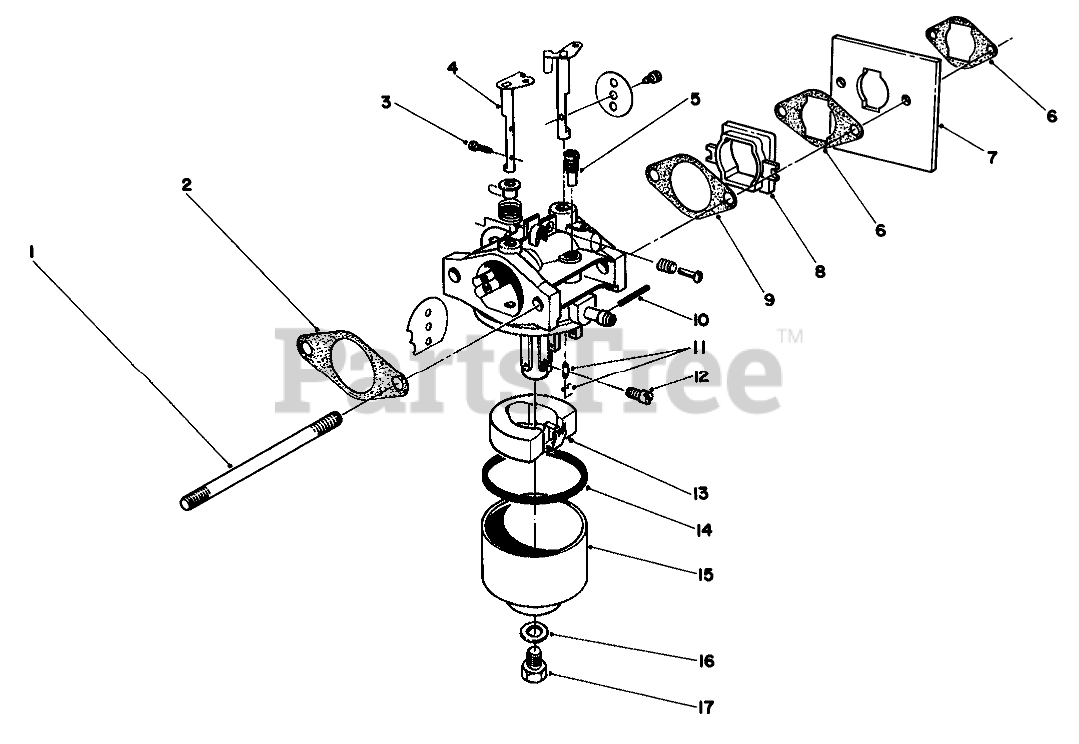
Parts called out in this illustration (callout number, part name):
1	CARB STUD BOLT
2	GASKET-AIR CLEANER
3	SCREW
4	SHAFT-CHOKE
5	PILOT JET
6	GASKET
7	SHIELD
8	INSULATOR
9	GASKET-CARB
10	Pin
11	NEEDLE VALVE ASM
12	MAIN JET (76.3)
13	FLOAT
14	GASKET
15	Bowl-Float
16	GASKET
17	Bolt
